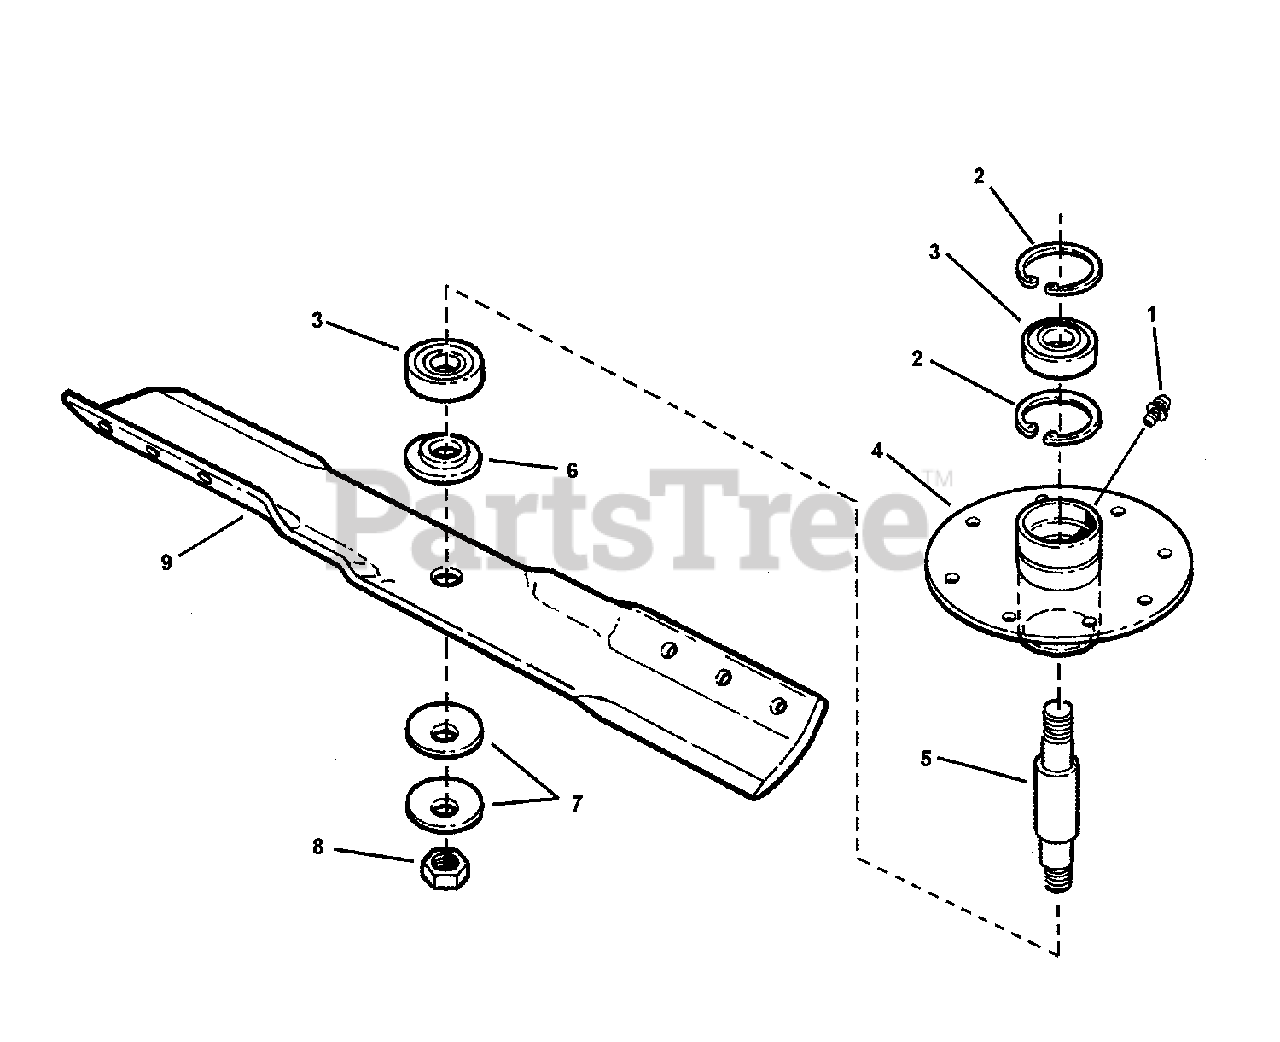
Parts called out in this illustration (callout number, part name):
1	FITTING, Lube (Press fit for .187 hole-no ball)
2	RING, 1-3/4" Retaining
3	BALL BEARING, 3/4" I.D.
4	WELDMENT, Spindle Housing
5	SHAFT, Spindle, 7.115" Long
6	WASHER, Spindle
7	WASHER, Belleville, 19/32" I.D. x 1-3/4" O.D.
8	NUT, 9/16-18 Hex Jam, GR B
9	BLADE, 19"
